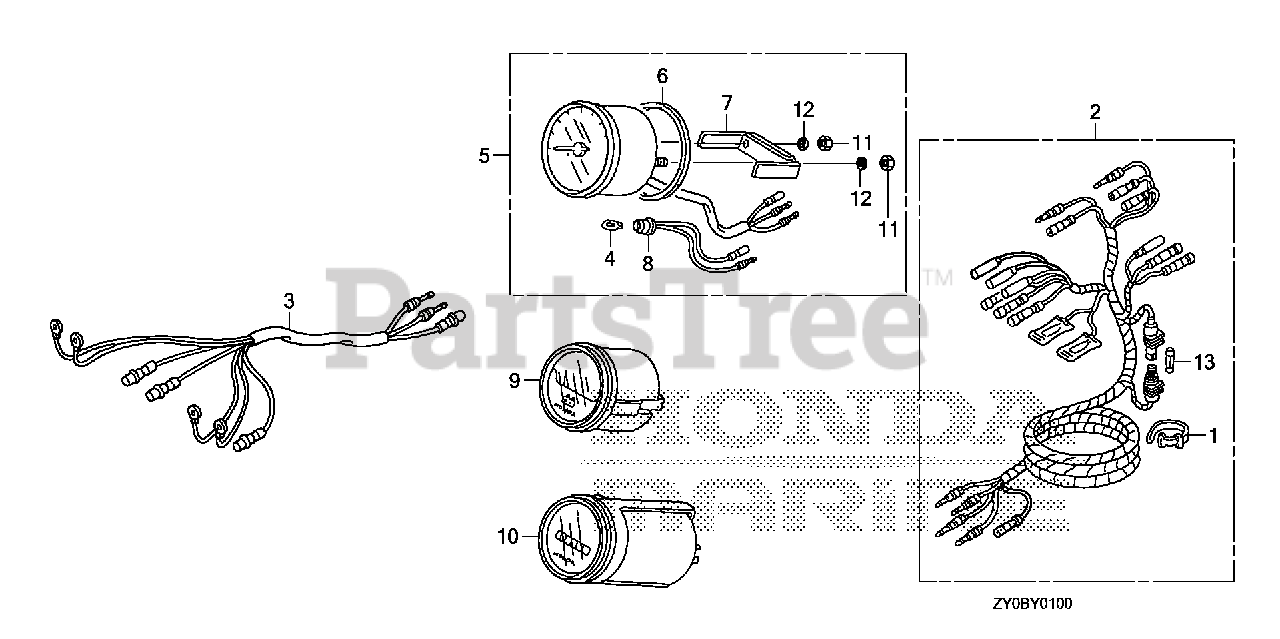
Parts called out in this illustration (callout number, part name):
1	BAND B1, WIRE
2	HARNESS ASSY., METER (A)
3	HARNESS ASSY., METER (B)
4	BULB, WEDGE BASE (T10) (12V 1.7W) (STANLEY)
5	TACHOMETER ASSY.
6	GASKET
7	BRACKET
8	SOCKET
9	METER ASSY., VOLT
10	METER ASSY., HOUR L.C.D.
11	NUT, HEX. (5MM)
12	WASHER, SPRING (5MM)
13	FUSE A (10A)
